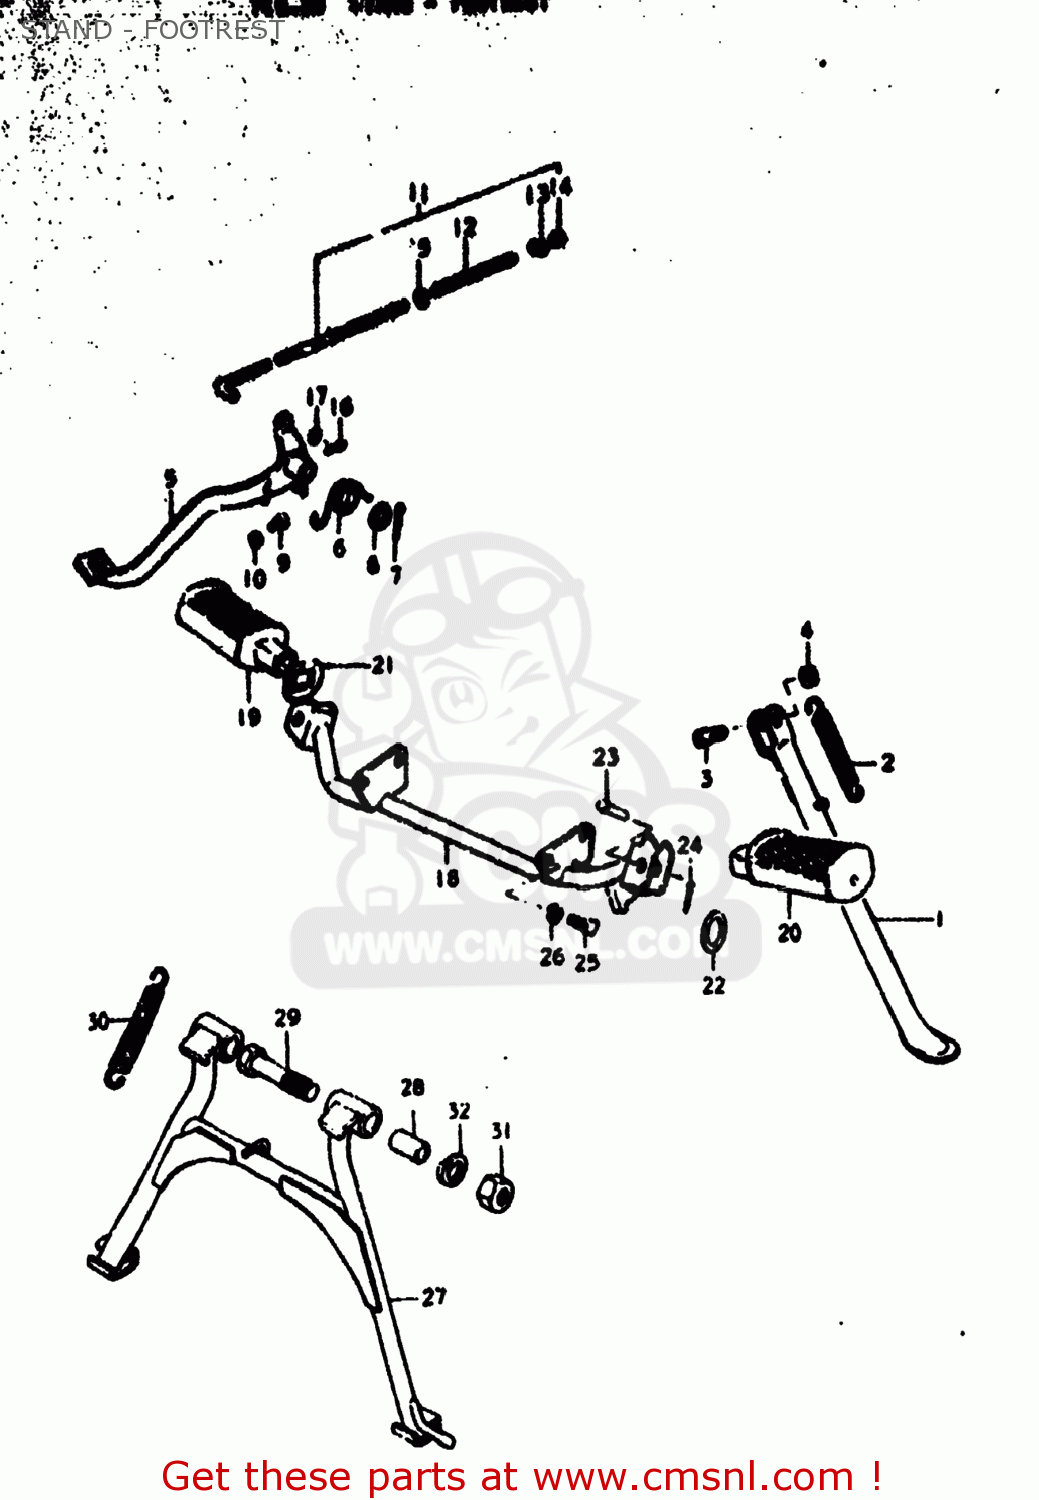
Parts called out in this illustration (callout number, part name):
1	STAND,SIDE
2	SPRING
3	BOLT
4	NUT
5	PEDAL,BRAKE
6	SPRING
7	COTTER PIN
8	WASHER
9	BOLT(6X18)
10	NUT
11	ROD ASSEMBLY,REAR BRAKE
12	SPRING
13	PIN(11X18)
14	NUT
15	WASHER
16	PIN 20X20
17	WASHER
18	BAR,FRONT FOOTREST
19	RUBBER,FOOTREST,RIGHT
20	RUBBER,FOOTREST,LEFT
21	WASHER
22	WASHER
23	PIN
24	PIN 20X20
25	BOLT
26	LOCK WASHER
27	STAND,CENTER
28	SPACER(10.5X16X30)
29	BOLT(10X48)
30	SPRING
31	NUT
32	LOCK WASHER
